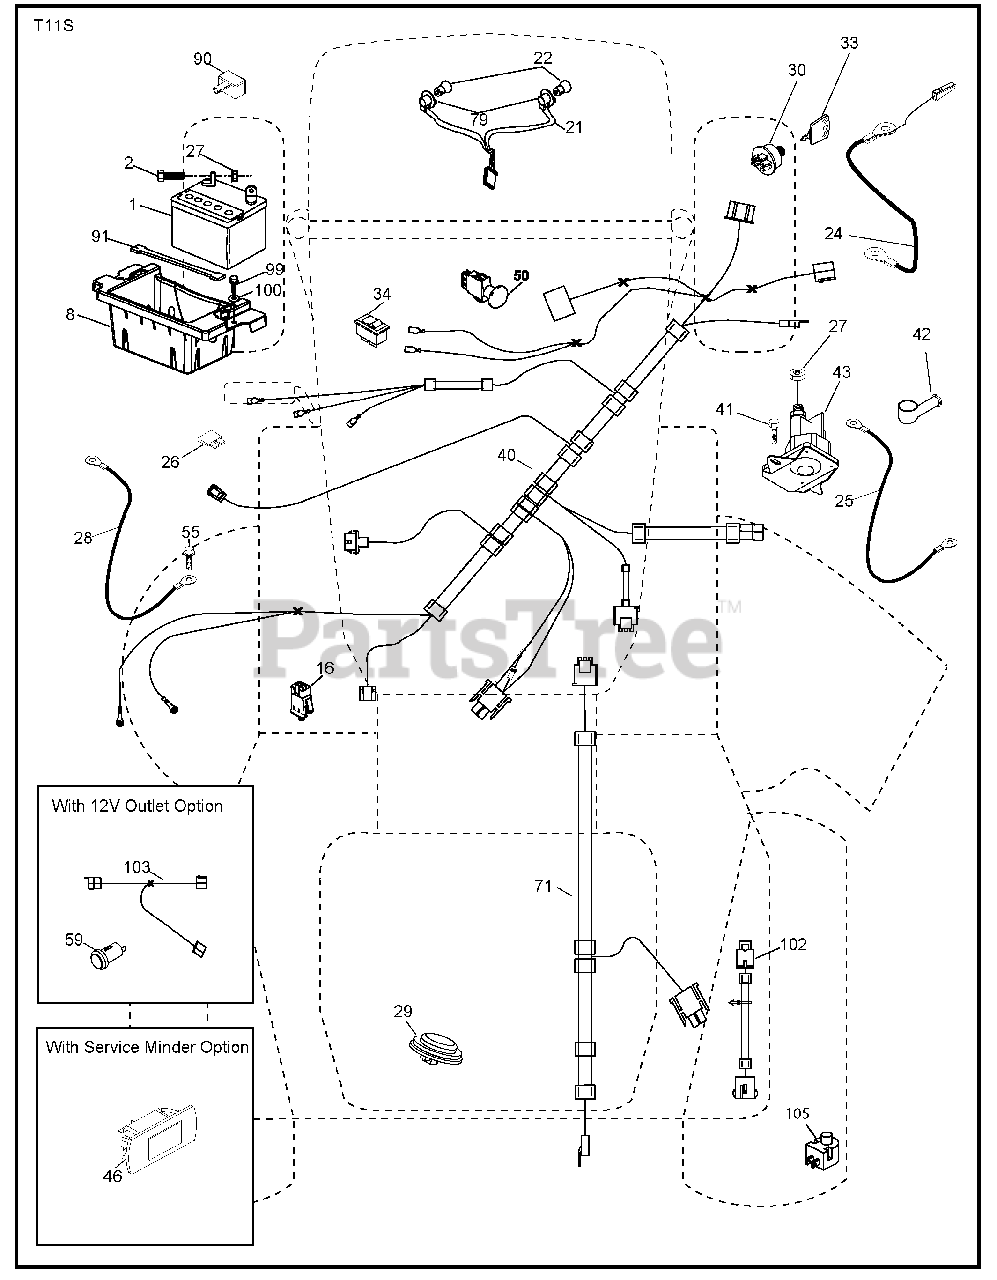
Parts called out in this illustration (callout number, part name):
1	Battery
2	Bolt Hex Head 1/4-20 x 3/4
8	Box Battery
16	Switch Interlock Push-In
21	Harness Socket Light w/4152J
22	Bulb Light
24	Cable Brty
25	Cable Starter
27	Nut Keps Hex 1/4-20 unc
28	Cable, Ground
29	Switch, Seat
30	Switch, Ign
34	Switch Light/Reset
40	Harness Ign. Dash
41	Screw Thd Cut 1/4-20 x 1/2
42	Cover, Terminal
43	Solenoid
46	Gauge Serviceminder Hrmtr
50	Switch PTO
55	Screw Thdrol 5/16-18 x 3/4 TYTT
71	Harness Ign.
79	Socket Asm. Bulb Twistlock
90	Cover Terminal
91	Strap Battery Mount Front
99	Screw Hexwsh Thdrol 1/4-20 x 3/4
100	Washer 9/32 x 7/8 x 16 Ga.
102	Harness Pigtail
105	Switch Reverse TT Pedal Control
